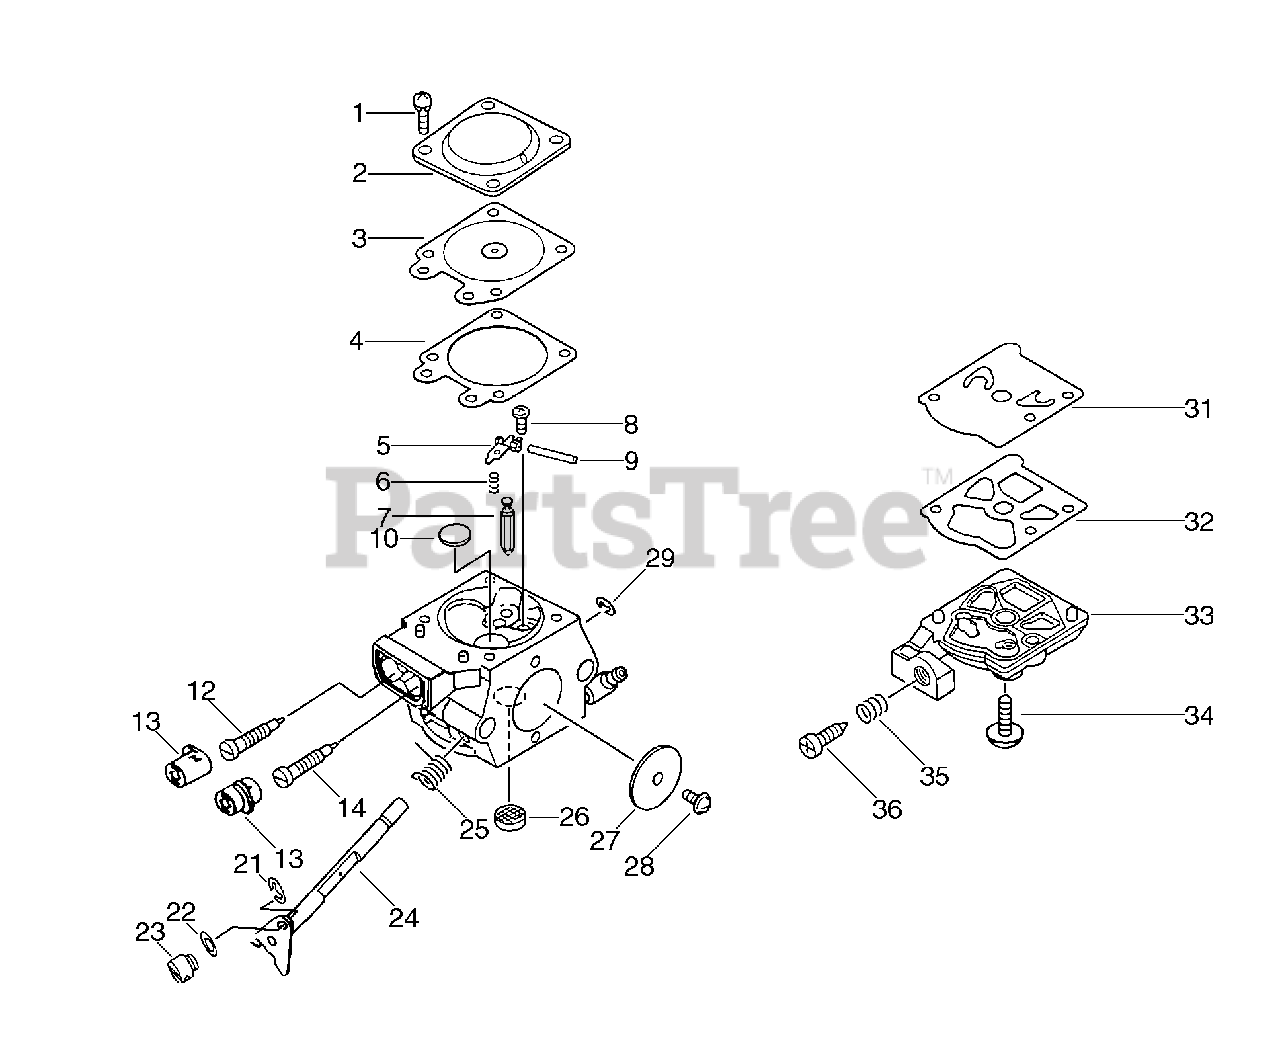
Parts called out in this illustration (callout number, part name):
2	COVER, METERING
3	DIAPHRAGM, METERING
4	GASKET, METERING
5	LEVER, METERING
6	SPRING, METERING LEVER
7	VALVE, INLET NEEDLE
8	SCREW, METERING LEVER PIN
9	PIN, METERING LEVER
10	PLUG, WELCH
12	NEEDLE - HIGH SPEED
13	CAP, LIMITER
14	NEEDLE - MIXTURE
21	RING, RETAINING
24	SHAFT, THROTTLE
25	SPRING, THROTTLE RETURN
26	STRAINER
27	VALVE, THROTTLE
29	RING, RETAINING
31	DIAPHRAGM, PUMP
32	GASKET, PUMP
33	COVER, PUMP
34	SCREW, PUMP COVER
35	SPRING, IDLE ADJUST
36	SCREW, IDLE ADJUST
